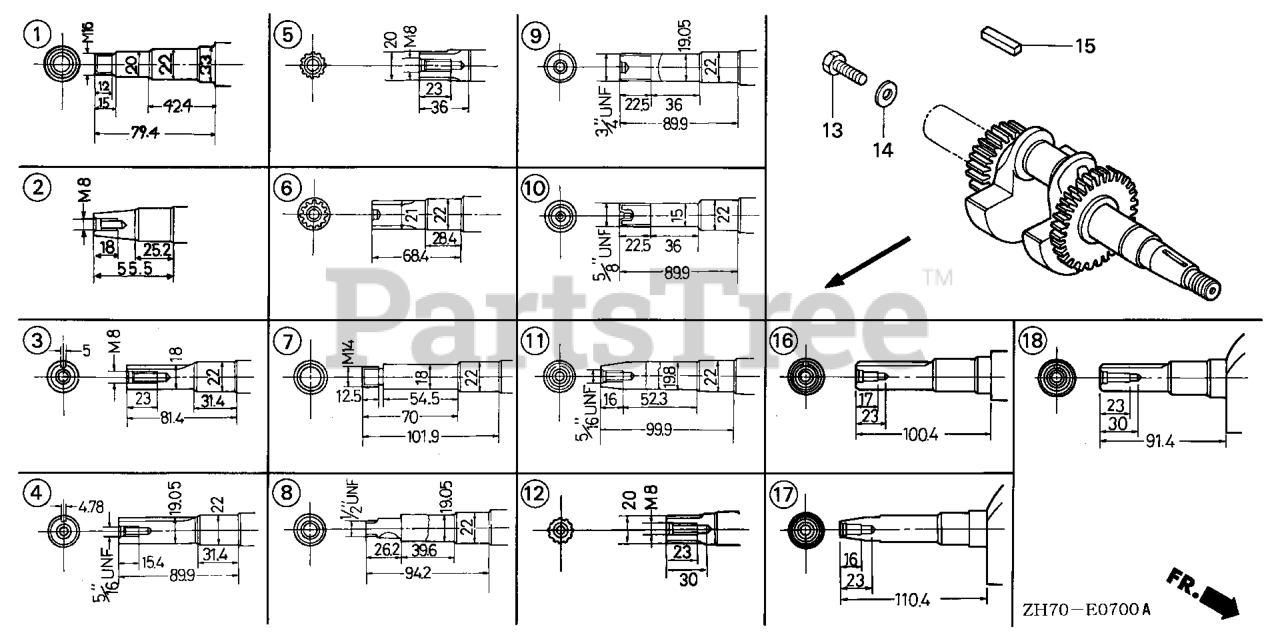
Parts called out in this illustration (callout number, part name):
3	CRANKSHAFT (S-TYPE)
13	BOLT, HEX. (8X25)
14	WASHER (8MM)
15	KEY (5X5X33)
